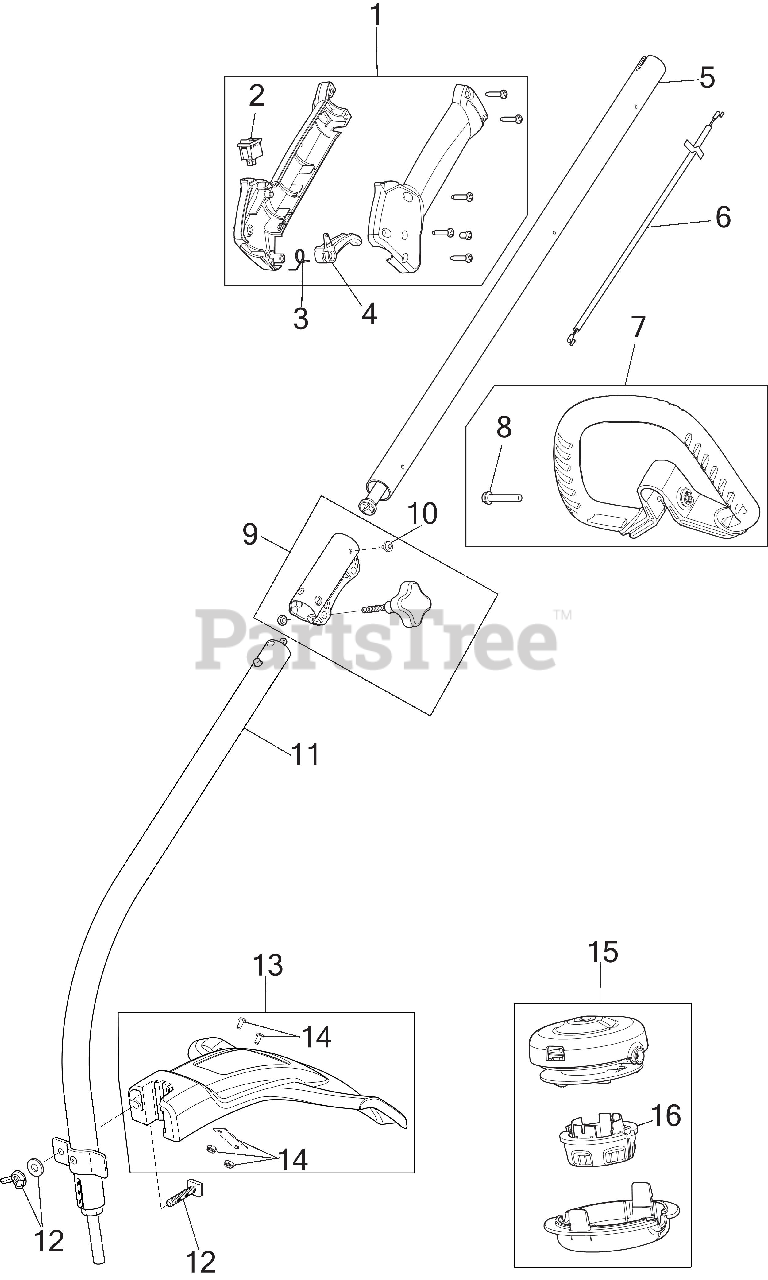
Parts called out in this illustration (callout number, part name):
1	THROTTLE HOUSING ASSEMBLY W/TRIGG
2	SW, MOMENTARY ON/O
3	SPRING, TRIGGER
4	THROTTLE TRIGGER (MTD RED)
5	BOOM ASSEMBLY UPR
6	THROTTLE CABLE
7	HANLE ASSEMBLY
8	BOLT 1/4-20X1 1/2
9	SPLIT BOOM COUPLER KIT
10	SCREW, 10-32X.250 TA
11	BOOM ASSEMBLY W/SHFT
12	BLADE GUARD MOUNTING HARDWARE
13	GUARD ASSEMBLY
14	ASSEMBLY, BLADE
15	HEAD ASSEMBLY CNT TB
16	BUMP KNOB BLACK
